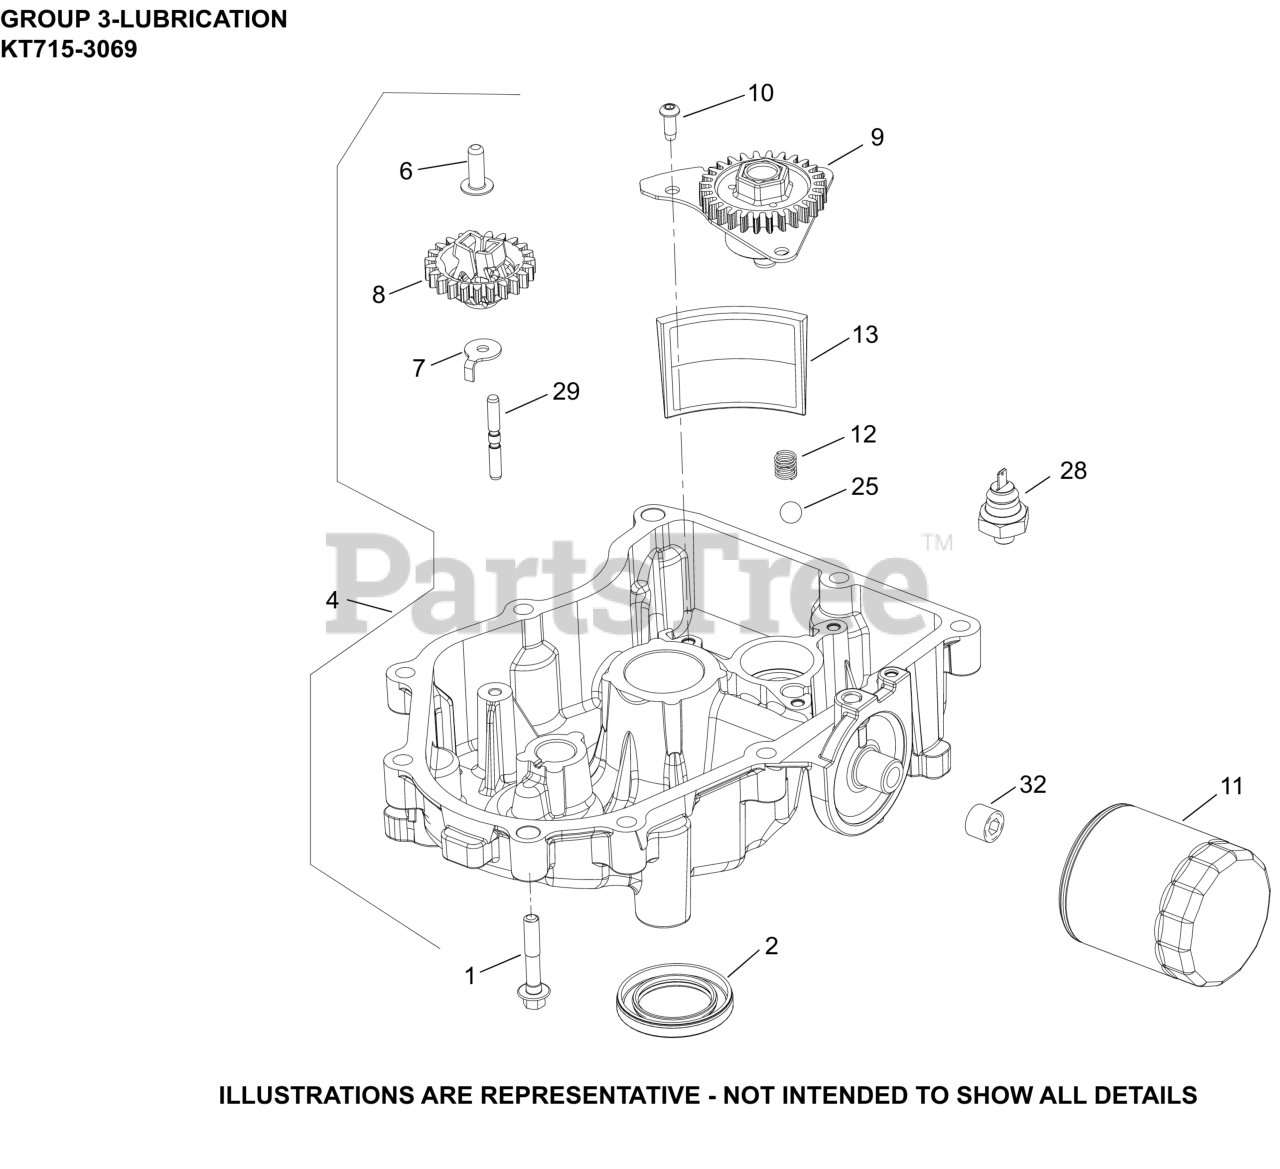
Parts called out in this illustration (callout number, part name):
1	SCREW, FLG M8X1.25X45
4	OIL PAN ASSEMBLY, (ROLLER BURNISHED)
6	PIN, GOVERNOR REGULATING
7	TAB, LOCKING
8	KIT, GOVERNOR GEAR
9	PUMP ASSEMBLY, OIL
10	SCREW, BUTTON HEAD
11	OIL FILTER
12	SPRING, COMPRESSION
13	SCREEN, OIL
25	PRESSURE RELIEF BALL
28	SWITCH, OIL PRESSURE(NC 3-6 PSI TO OPEN)
29	SHAFT, GOVERNOR GEAR
32	PLUG, PIPE CTSK 3/8"
